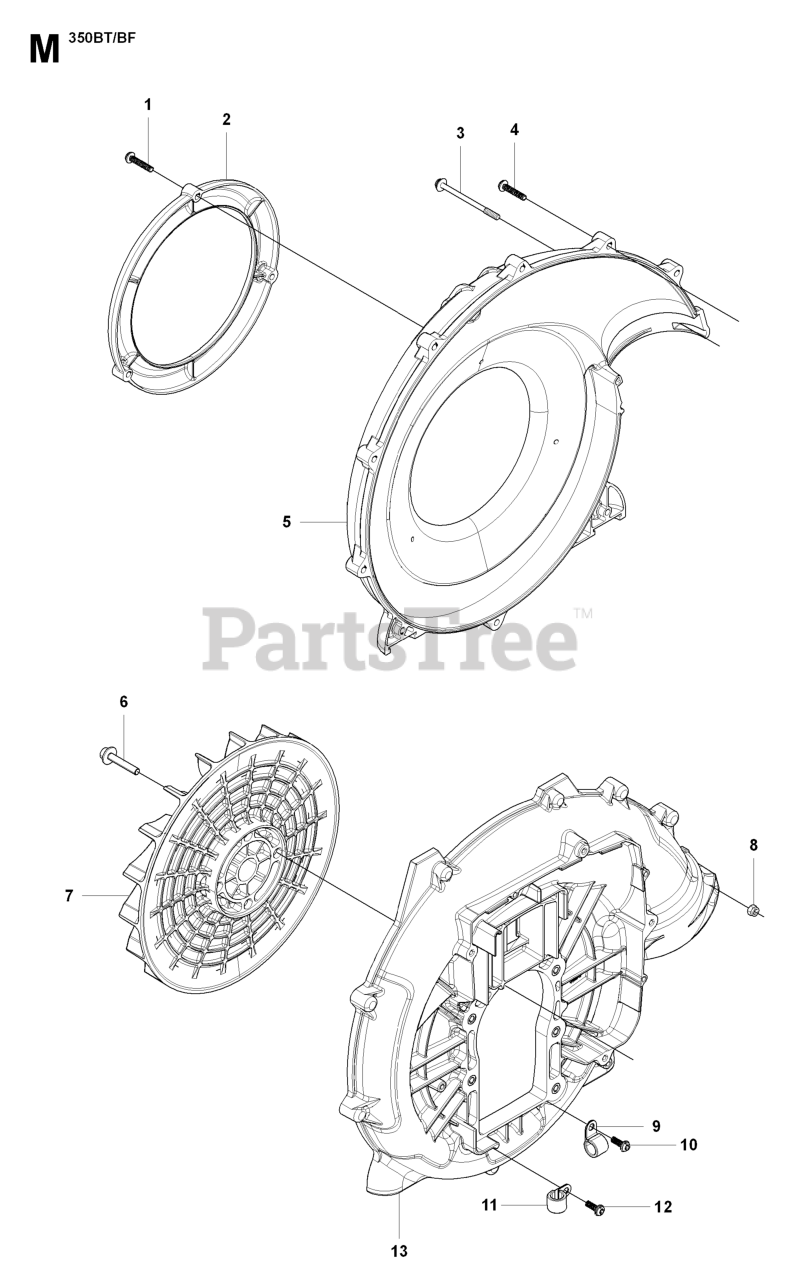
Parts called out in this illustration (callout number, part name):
5	VOLUTE COVER
7	IMPELLER FAN
11	CLAMP
13	FAN HOUSING VOLUTE
